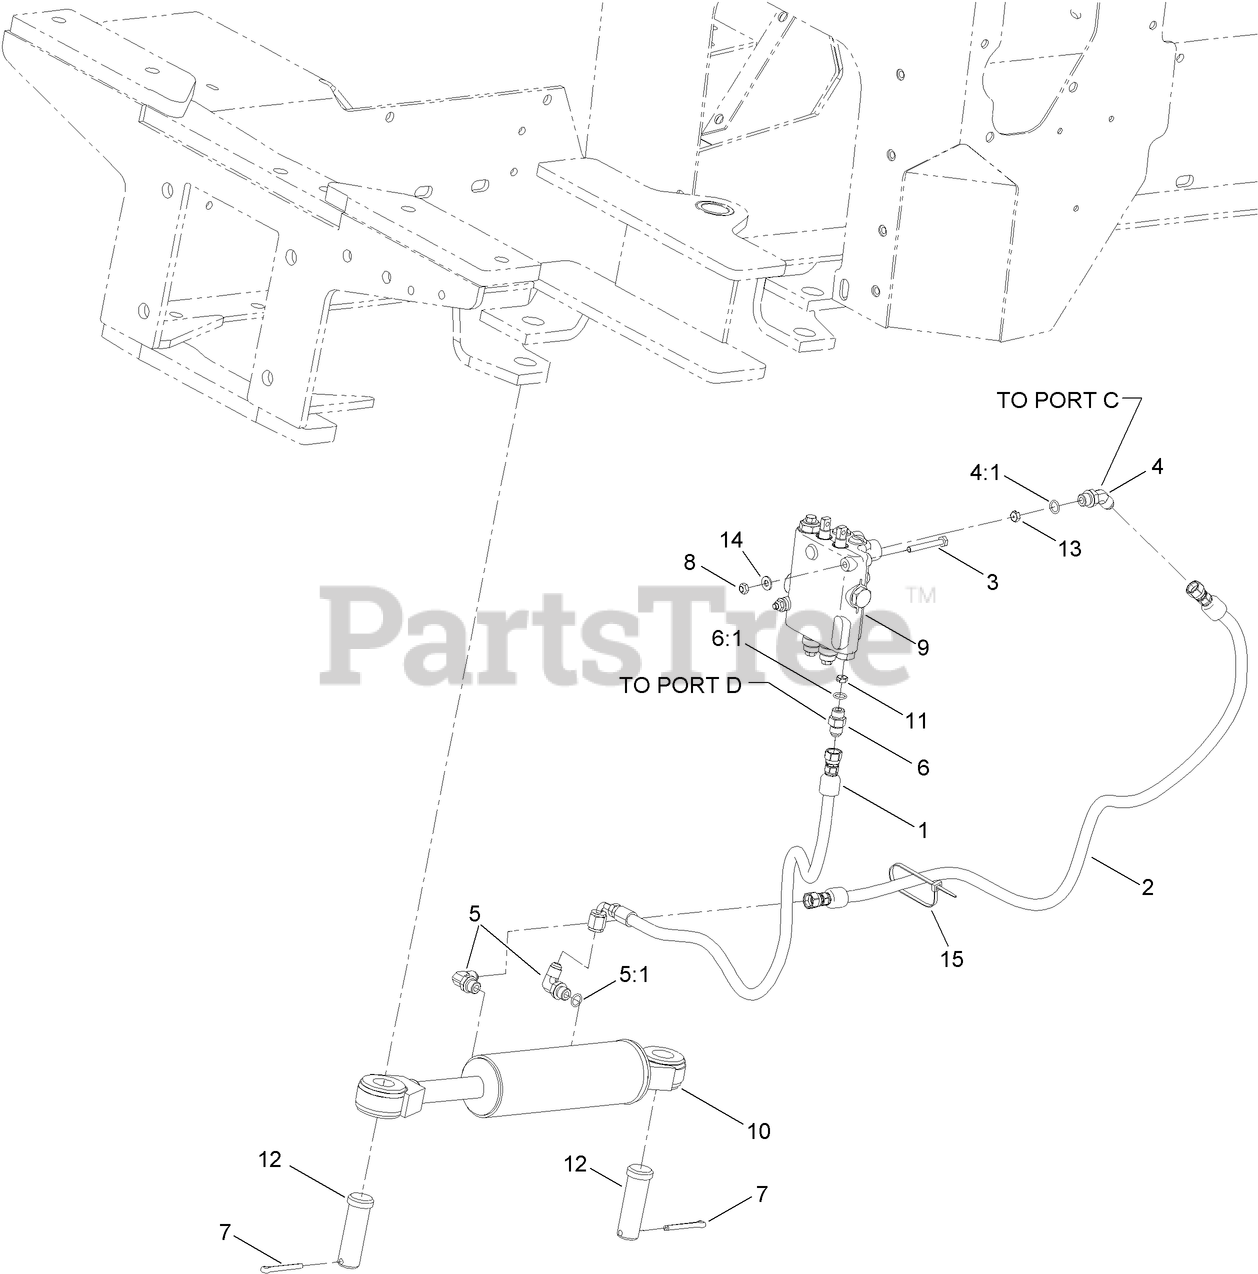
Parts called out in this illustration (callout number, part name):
1	HOSE ASM
2	HOSE ASM
3	SCREW-HH
4	FITTING-ELBOW, 45 DEG
4:1	O-RING
5	FITTING-ELBOW, 90 DEG
5:1	O-RING
6	FITTING-STRAIGHT
6:1	O-RING
7	PIN-COTTER
8	NUT-LOCK, CONE
9	HYD STEERING VALVE ASM
10	HYD CYLINDER ASM
11	PLATE-ORIFICE
12	PIN-CLEVIS
13	PLATE-ORIFICE
14	WASHER-FLAT
15	TIE-CABLE
